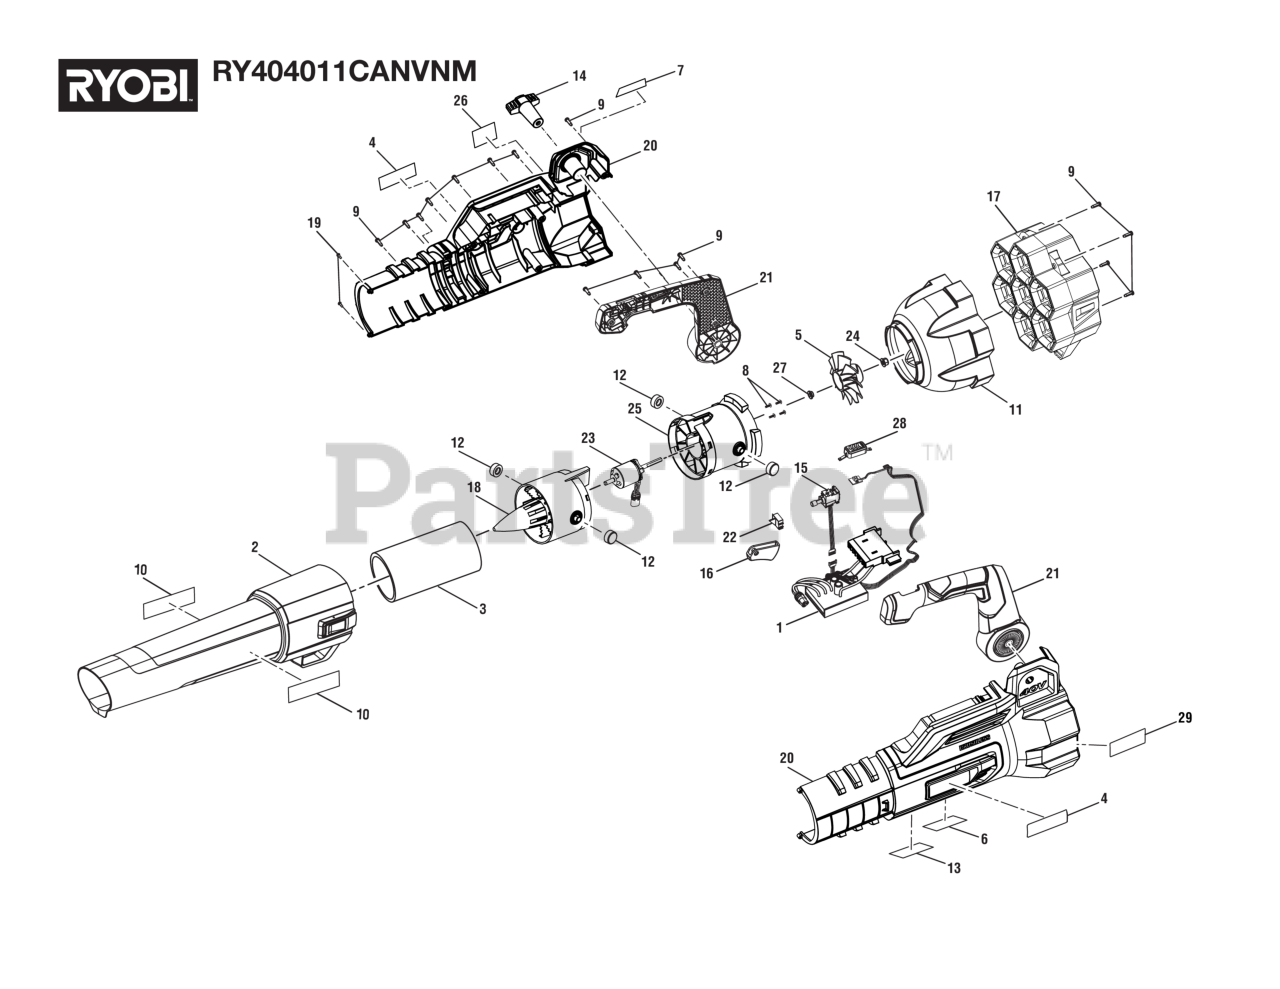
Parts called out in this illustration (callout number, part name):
1	Motor Controller and Battery Connection Assembly
2	Blower Tube Assembly (Includes Key No. 10)
3	Sound Dampening Foam
4	Logo Label
6	Warning Label (French and Spanish)
7	Warning Icons Label
8	SCREW, M3.0X0.5-6h PWH PHILIPS B \ L=8MM
9	Screw (M4 x 14 mm, T15 Torx Pan Hd.))
10	Whisper Series Label
11	Inlet Bell Assembly
12	Rubber Cap
13	Data Label
14	Handle Knob
15	Variable Speed Switch
17	Inlet Cover Assembly
19	Screw (M3 x 8 mm, Pan Hd., Pan Hd)
20	Housing Assembly
21	Handle Assembly
22	Switch Cap
24	Flange Lock Nut (M6 x 1 mm)
25	Motor Mount
26	Warning and Warning Icons Label (English)
28	Turbo Button
29	40V HP Brushless Label
